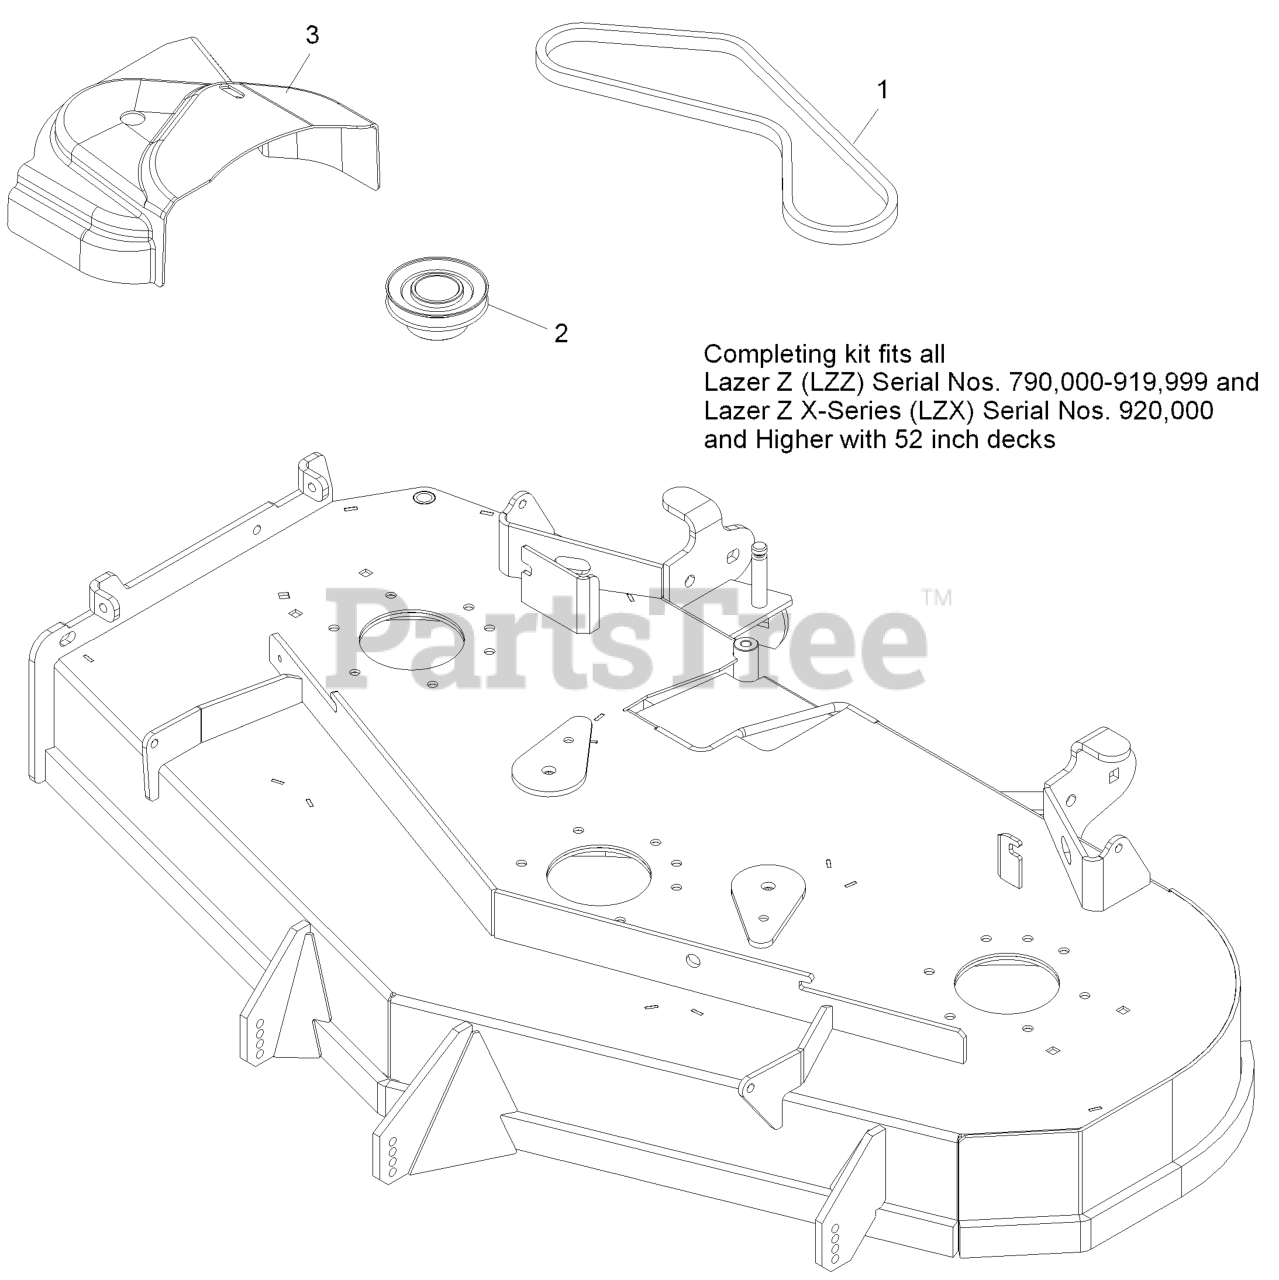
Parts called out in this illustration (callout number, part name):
1	BELT, BLOWER 52"DECK
2	SHEAVE,DRIVE LZUV 526
3	COVER,BELT UV 52
